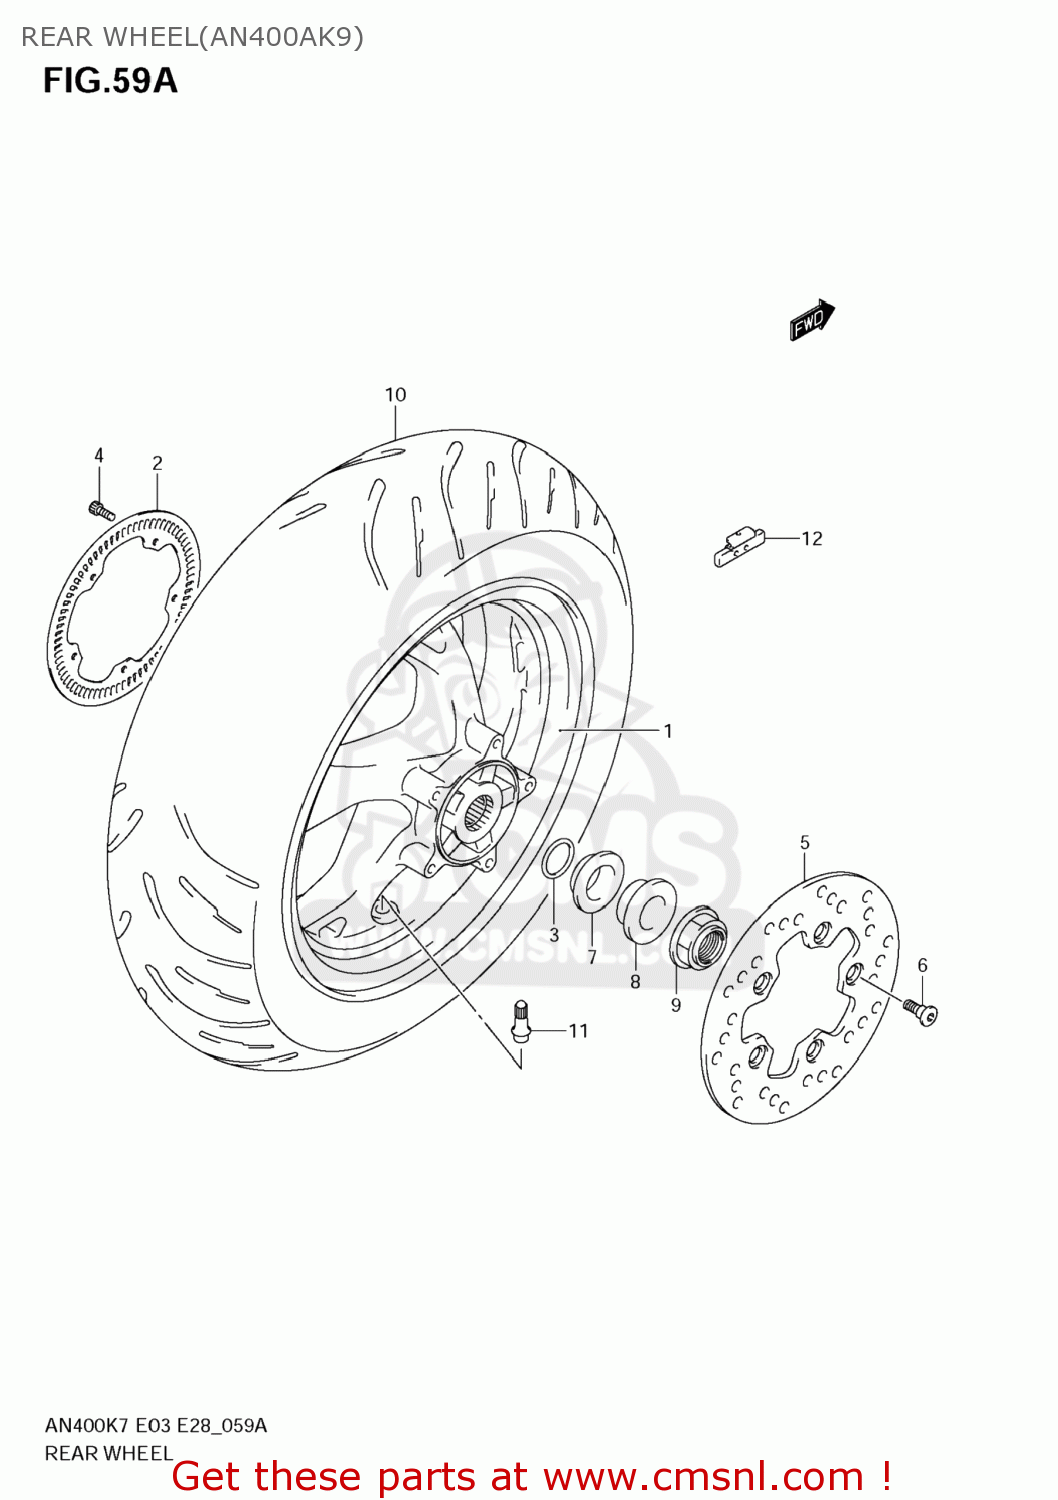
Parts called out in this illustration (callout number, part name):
1	WHEEL,RR(13M/CXMT4.00)
2	RING,SPEED SENSOR RR(72T)
3	O RING(D:2,ID:24.5)
4	BOLT
5	DISC,RR BRAKE
6	BOLT(8X21)
7	SPACER,RR AXLE INNER
8	SPACER,RR AXLE OUTER
9	NUT
10	TIRE,RR(150/70 13M/C 64S)
11	VALVE ASSY,WHEEL RIM(TR412)
12	WEIGHT,WHEEL BALANCE 10G
